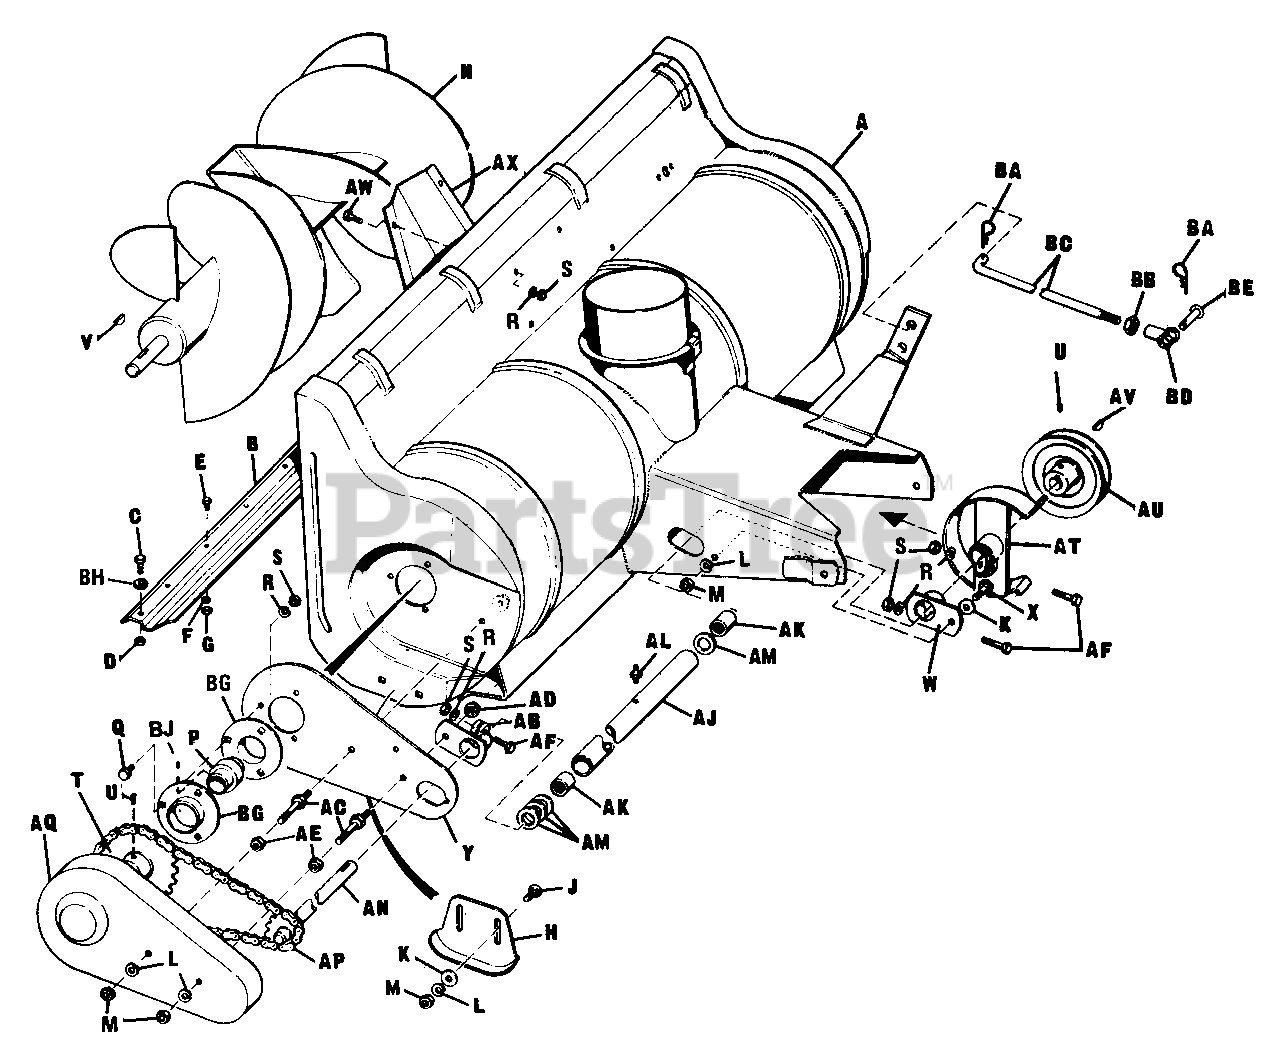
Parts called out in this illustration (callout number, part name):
A	Body Assembly
B	Body Scraper
C	Hex. Cap Screw, 5/16"-18 x 5/8"
D	Full Lock Hex. Nut, 5/16"-18
E	Hex. Cap Screw, 1/4"-20 x 5/8"
F	Lock Washer, 1/4"
G	Full Hex. Nut, 1/4"-20
J	Carriage Bolt, 3/8"-16 x 3/4"
K	Plain Washer, 3/8"
L	Lock Washer, 3/8"
M	Full Hex. Nut, 3/8"-16
N	Rotor Assembly
P	Bearing Cartridge w/713509 Set Screw
Q	Hex. Cap Screw, 5/16"-18 x 3/4"
R	Lock Washer, 5/16"
S	Full Hex. Nut, 5/16"-18
T	Rotor Sprocket
U	Set Screw, 5/16"-18 x 5/16"
W	Support Assembly Clamp
X	Hex. Cap Screw, 3/8"-1 x 1"
Y	Side Plate
AB	Support Assembly Clamp
AD	Nut, Flange, 3/8"-16
AE	Full Lock Hex. Nut, 3/8"-16
AF	Hex. Cap Screw, 5/16"-18 x 1-1/2"
AJ	Bearing Housing
AK	Needle Bearing
AL	Grease Fitting
AN	Shaft Assembly
AQ	Chain Guard
AT	Belt Guard Assembly
AV	Key, 3/16" Dia. x 3/4"
AW	Hex. Cap Screw, 5/16"-18 x 5/8"
BA	Spring Clip
BB	Full Hex. Nut, 1/2" x 20
BC	Front Lift Rod
BD	Adjusting End Yoke
BG	Bearing Flange
BJ	Set Screw 1/4"-28 x 1 1/4 LG
